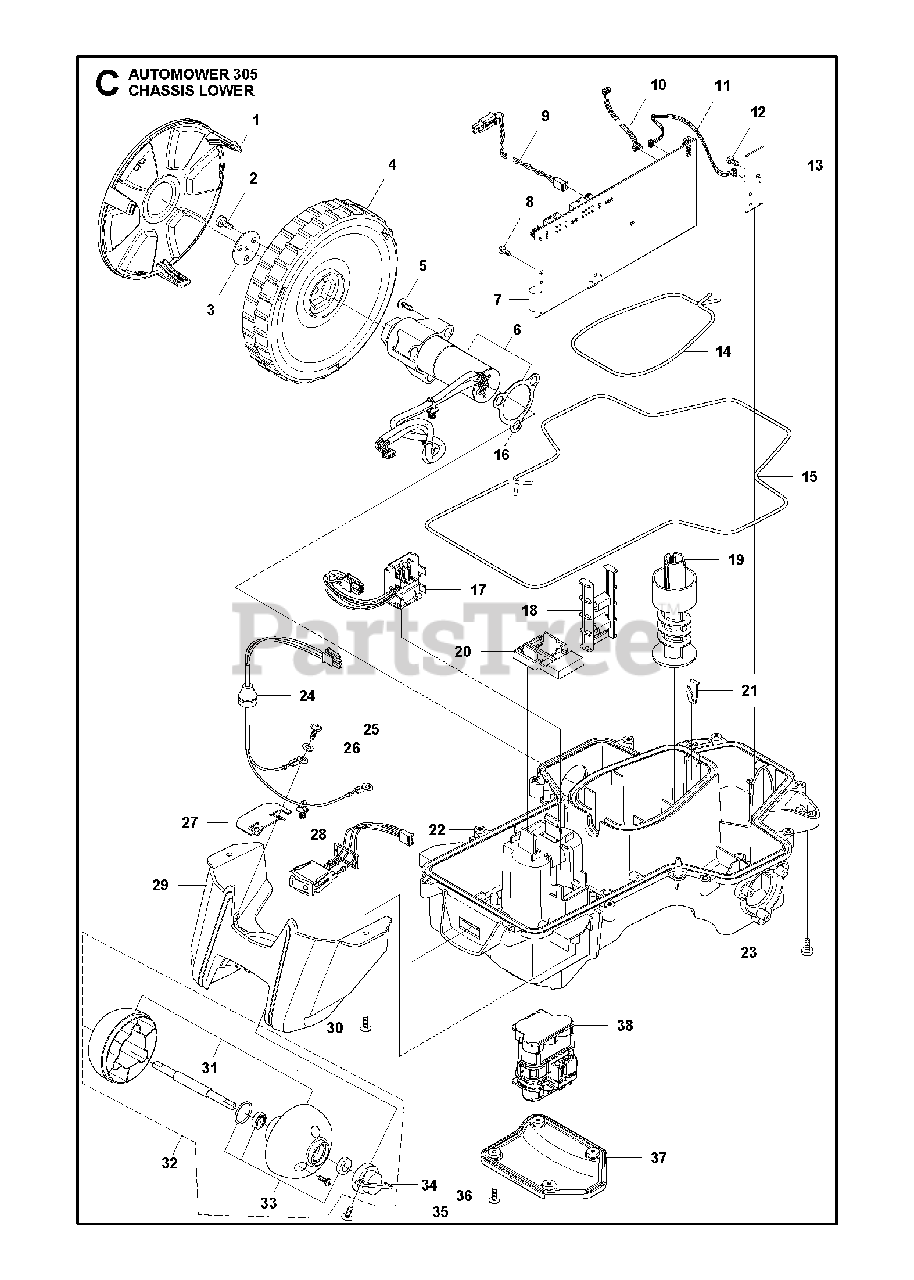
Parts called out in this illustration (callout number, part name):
2	SCREW ITXPANM M5X12 8
3	WASHER DRIVE WHEEL
5	SCREW 14MM
8	SCREW
9	LOOM BUZZER EXTENSION
12	SCREW
14	SEALING STRIP P1
15	SEALING STRIP P1 CHAS
16	GASKET MOTOR FLANGE
17	LOOM BATTERY 18 V LLI
18	GUIDE RAIL MOTOR BOWL
19	SCREW HEIGHT ADJUSTME
20	LOCK BATTERY PLUG
21	LOCKING SPRING
23	SCREW ITXPANM M5X12 8
25	SCREW 14MM
26	FIBER WASHER
30	SCREW 14MM
33	REAR WHEEL BEARING AN
34	BEARING HOUSING REAR
35	SCREW 14MM
36	SCREW ITXPANT
37	Battery Cover
